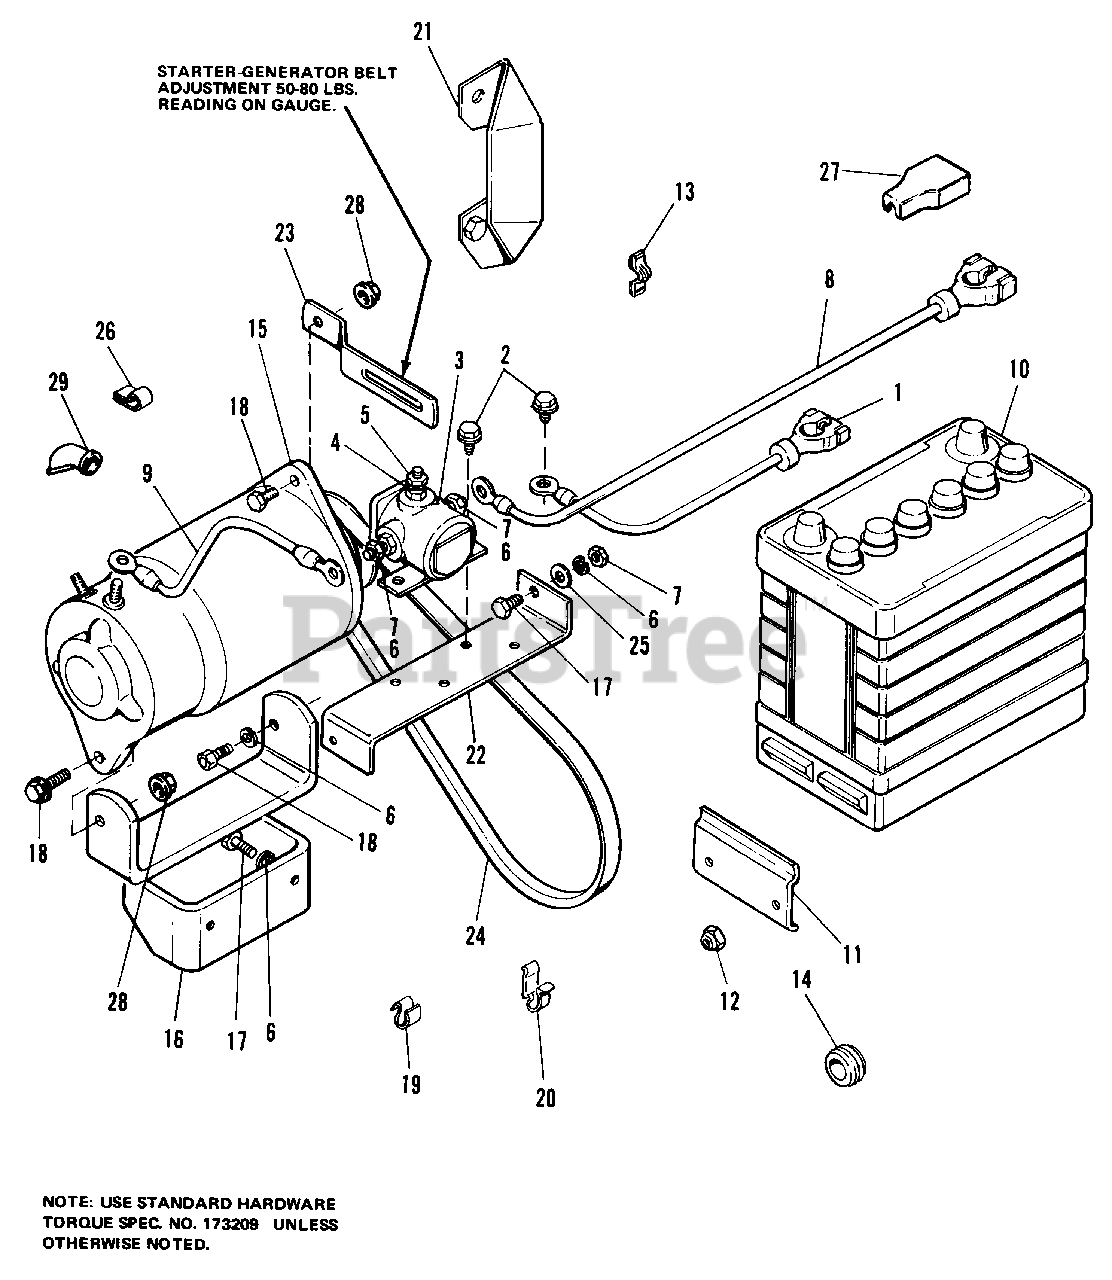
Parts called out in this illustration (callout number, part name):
1	CABLE, Battery to Ground
2	SCREW, Taptite, 1/4-20 x 1/2
4	LOCKWASHER, No. 10
5	NUT, Hex, No. 10-32
6	LOCKWASHER, 5/16
7	NUT, Hex, 5/16-18
8	CABLE, Battery to Solenoid
9	CABLE, Solenoid to Starter
12	NUT, Elastic, 5/16-18
13	CLIP, Wire
15	MOTOR, Generator
16	SUPPORT ASSEMBLY
17	CAPSCREW, Hex Hd., 5/16-18 x 3/4
18	CAPSCREW, Hex Hd., Flange, Whizlock 5/16-18 x 1-1/4
19	CLIP, Tinnerman
20	CLIP, Tinnerman
21	PULLEY GUARD ASSEMBLY
23	ARM, Adjusting
24	V-BELT, 39.12"
25	WASHER, 5/16
26	CLIP, Cable
27	PROTECTOR, Terminal
28	NUT, Flange, Whizlock 5/16-18
29	COVER, Terminal
